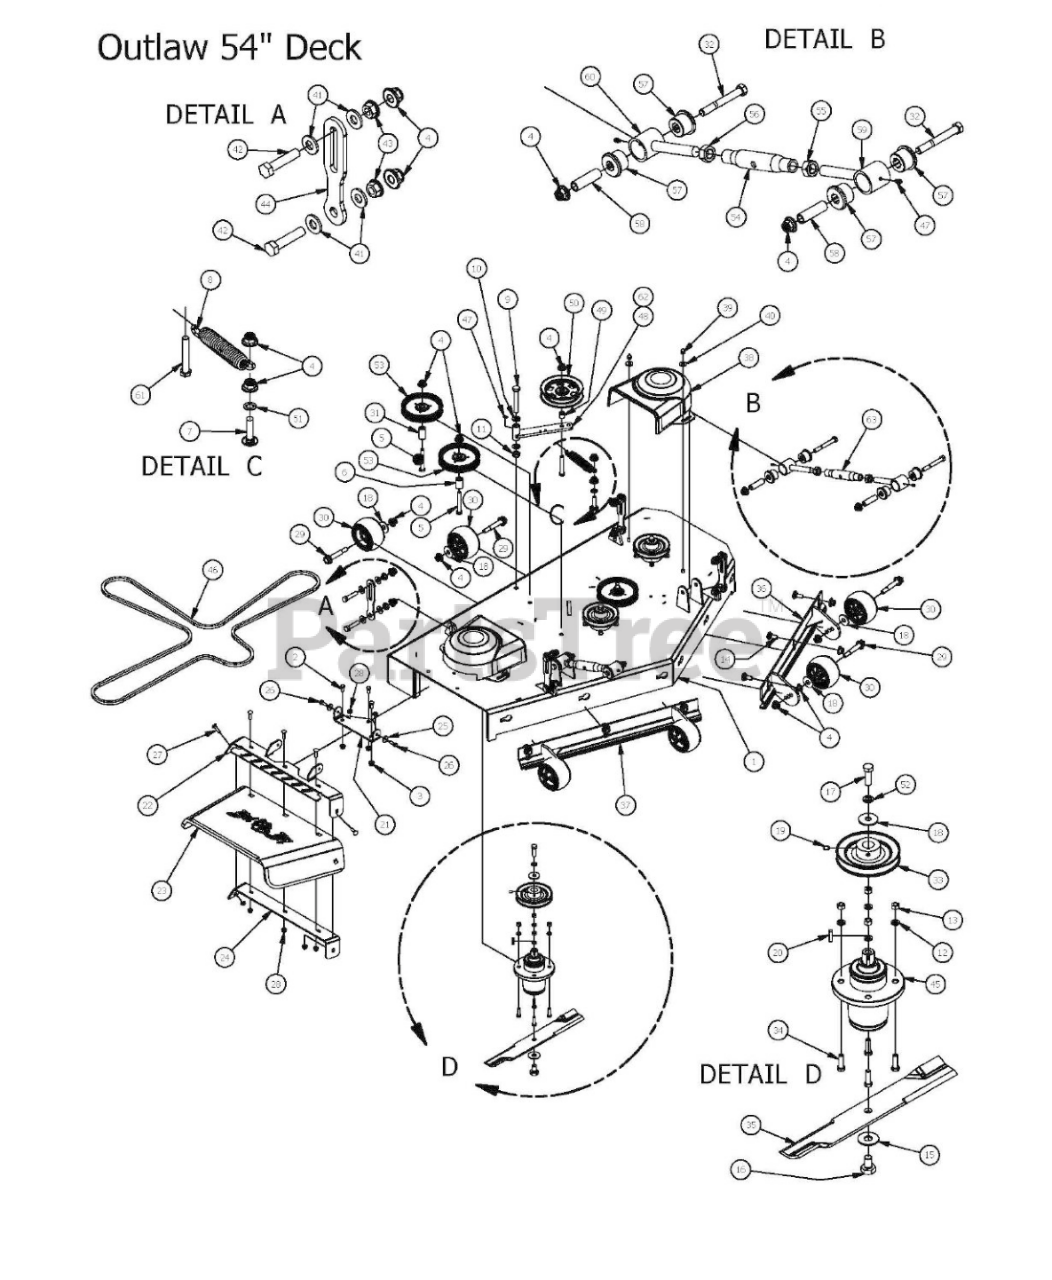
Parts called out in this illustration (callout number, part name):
1	2015 54" Deck
2	3/8" x 3/4" Hex Bolt
3	3/8" Flange Nut
4	1/2-13 Nylon Flange Nut
5	1/2 x 3 1/2 Flange Bolt Grade 8
6	Idler Pulley Standoff
7	1/2 x 2" Carriage Bolt
8	2015 Deck Idler Spring
9	5/8" x 4" Hex Bolt
10	630 ID Plastic Washer
11	5/8-11 Nylon Insert Jam Half Nut
12	3/8 Lockwasher Zinci
13	3/8-16 Hex Nuts Zinc
14	1/2" x 1 1/4 Carriage Bolt
15	5/8" Flat Washer
16	5/8" x 1 1/2" Grade 8 Hex Bolt (Fine)
17	1/2"-20 x 1 1/2-Grade 5 Fine Thread Bolt
18	1/2" Belleville Washer
19	5/16 Set Screw
20	1/4" x 1" Key
21	Discharge Chute Hanger (deck mounted)
22	60" Discharge Chute Upper Hanger
23	Rubber Discharge Chute
24	60" Discharge Lower Bracket
25	*360 ID Plastic Washer
26	5/16" x 1" Bolt
27	5/16" x 1 1/4" Carriage Bolt
28	5/16" Nylock Flange Nut Zinc
29	Deck Wheel Bolt
30	Anti-Scalp Roller
31	1 3/4" Pulley Spacer
32	1/2" x 4" Bolt (Grade 8)
33	5.25 Deck Spindle Pulley
34	3/8" x 1 1/4" Hex Bolt
35	54" Deck Fusion Blade For Outlaw
36	54 Deck Adustable Front (Left)
37	54 Deck Adustable Front (Right)
38	Pulley Cover
39	Acorn nut-pulley Cover
40	360 ID Plastic Washer-Black
41	505 Nylon Spacer
42	1/2-13x 2-1/4 GR Hex Bolts
43	1/2" Flange Nut
44	Deck Hanging Tab
45	OUTLAW SPINDLE ASSEMBLY
46	60" ZT Deck Belt
47	1/4" Press in Grease Fitting
48	Deck Idler
49	Spacer 3/4 OD x 1/2 ID x 314 Length
50	5" Idler Pully
51	517 Square Hole Round Washer
52	1/2" Lock Washer
53	5-3/4 Idler Pulley-Capitol Stampings
54	2015 Outlaw Toplink Body
55	3/4-10 Left Handed Hex Nuts Zinc
56	3/4-10 Hex Nuts Zinc
59	Tum Left-Handed
60	Right-Handed End
61	1/2-13 x GR 5 Hex Bolt Zinc
62	Deck Idler Assembly - Includes parts: 4,47,48,49,50,51
63	Tumbuckle Assembly
